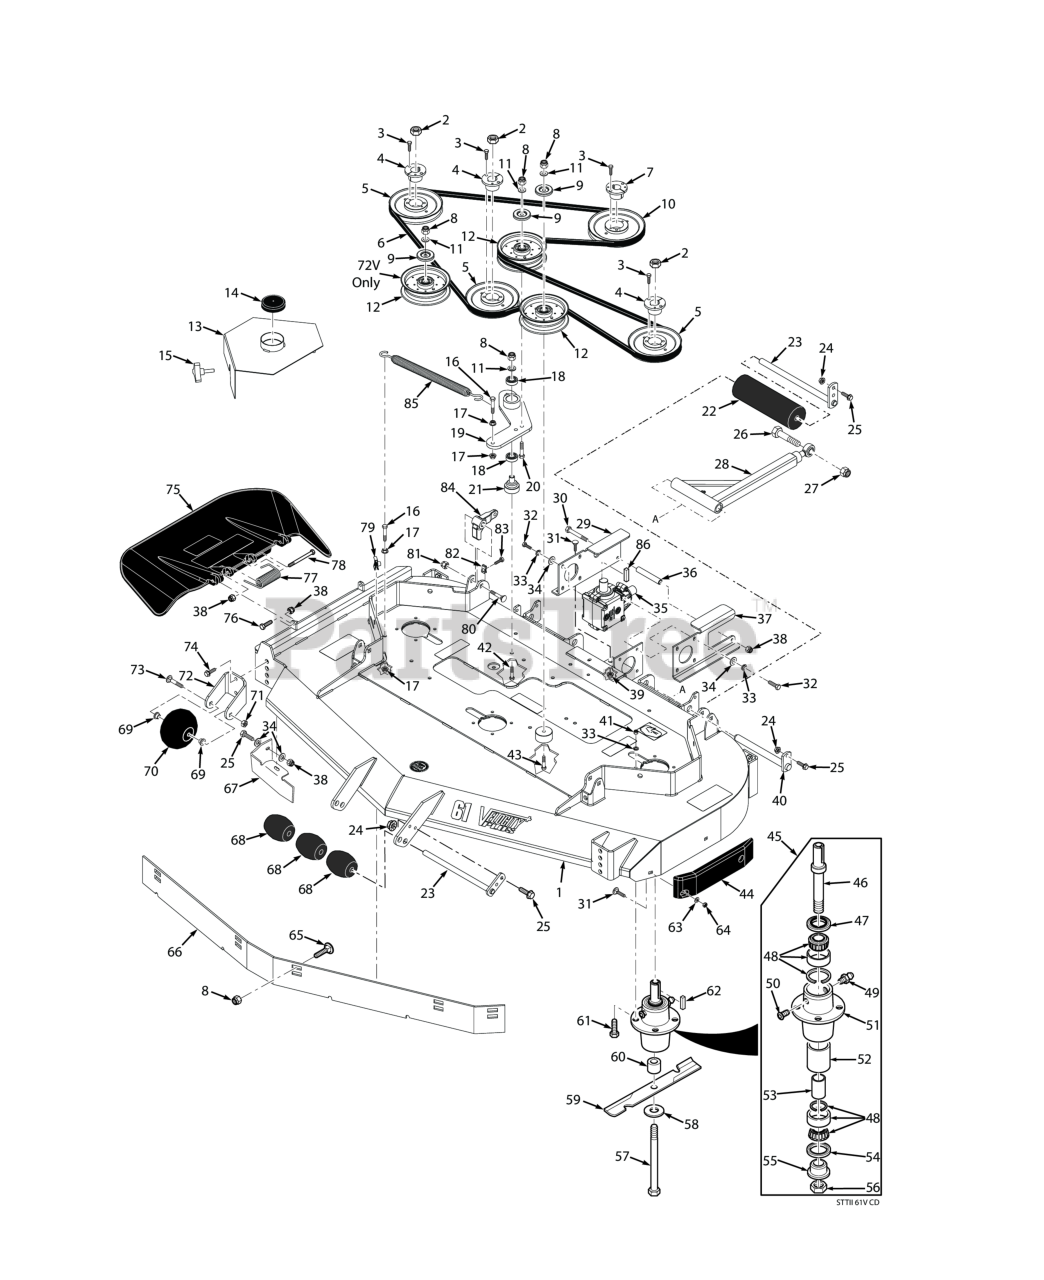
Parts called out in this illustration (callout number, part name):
1	Cutter Deck w/Decals - 72V
2	Hex Locknut, Elastic Stop, 3/8-16
3	Bolt, Hex Head 1/4-20 x 1" Grade 8 Black
4	Hub, Tapered 1-1/8" Bore
5	Pulley, 6.35 O.D. (Diesel Engine)
6	Belt, Cutter Deck Drive - Kubota
7	TAPERED HUB, 1.00" BORE
8	HEX NUT, ELASTIC STOP LOCK, 3/8-16
9	Quick Pin, 5/16" Dia.
10	Pulley, 6.75 O.D. - 61"
11	Flatwasher, 3/8 (.391 x .938 x .105 HD) Grade 8
12	Idler Pulley, Belt Clutch
13	Belt Cover, 61V (incl. #14)
15	Knob, w/stud 3/8-16 x 1-1/4"
16	Bolt, Hex Head 3/8-16 x 1-1/2" Grade 8 Black
17	NUT, 3/8-16 SERRATED FLANGE HEX HEAD
18	BEARINGS, BALL, NEUTRAL RETURN
19	Idler Arm, Cutter Deck
20	Capscrew, Hex Head 3/8-16 x 2.75"
21	Pivot, Idler - Short
22	Wheel, Anti-ScalpRelief Fitting, Tapered Spindle
23	Shaft Weldment, Guide Roller
24	Nut, Flange Head Elastic Stop 5/16-18
25	Bolt, Heax Head 5/16-18 x 1" (48V / 52V)
26	BOLT, HEX HEAD 5/8-11 X 4-1/2"
27	HEX LOCKNUT, ELASTIC STOP, 5/8-11
28	Push Arm (Includes 64,60,62)
29	Mounting Plate
30	Bolt, 5/16-18 x 4-3/4" Hex Head
31	Bolt, 5/16-18 x .75 RHSN Carriage
32	Bolt, Heax Head 5/16-18 x 1" (48V / 52V)
33	Lockwasher, 5/16 (.317 x .586 x .078) Helical Spring
34	Flatwasher, 5/16-.375 x .875 x .083 (35BV & 37BV-EFI)
35	Gearbox Assembly, Deck Drive
36	Spacer, Gearbox Mount
37	Mounting Plate
38	HEX NUT, ELASTIC STOP LOCK, 5/16-18
39	Nut, Serrated Flange 5/16-18 (Right Front Engine Mounting, Briggs and Kohler Only)
40	Shaft Weldment, Pusharm
41	Lock Nut, 5/16-18 Elastic Stop Grade 8
42	Bolt, Hex Head 3/8-16 x 3" - 52"
43	Capscrew, Hex Head 3/8-16 x 3-3/4"
44	Pad, Deck Wear
45	Cutter Spindle Assembly
46	Spindle Shaft, Tapered Brng
47	SEAL, 2.00 O.D. X 1.50 BORE
48	Tapered Bearing Set (Two Bearings W/Race)
49	GREASE FITTING, STR. 1/4-28 SELF TAP.
50	RELIEF FITTING, TAPERED BEARING SPINDLE
51	Housing, Spindle
52	Spacer, Outside, Cutter Spindle
53	SLEEVE, CUTTER SPINDLE
54	Seal, 2.00" O.D. x 1.625" Bore
55	SPINDLE BUSHING, BOTTOM
56	Nut , Spec ial 1 -1/ 1 6 - 1 8
57	BOLT, HEX HEAD, 5/8-11 X 9-1/2 GR.5
58	Flatwasher, 5/8-.688 x 1-3/4 x .134 HD
59	Cutter Blade, 21" Standard
60	Spacer, Spindle Bottom
61	Bolt, Hex Head 5/16-18 x 1-3/4" Grade 8
62	Key, 1/4 x 1/4 x 2.0"
63	Flatwasher, 5/16-.344 x .688 x .065 (48V / 52V)
64	Nut, Center Lock, 5/16-18(32)
65	Carriage Bolt, 3/8-16 x 1.0"
66	Baffle Custom-Cut, 61V (7-Position)
67	Turbo Baffle, Bolt On
68	Wheel, Anti-Scalp
69	Bushing, .376" I.D. Oilite
70	Bolt, Carriage 3/8-16 x 4"
71	Bolt, Hex Head 3/8-16 x 1" Ser. Flg.
72	Bracket, Anti-Scalp Wheel
73	Bolt, Hex Head 3/8-16 x 3-1/2"
74	Capscrew, 3/8-16 x 1.0" Serrated Flange Hex Hd
75	Discharge Chute Advantage - Large
76	Bolt, Hex Head 5/16-18 x 1-1/2" - Front
77	Spring, Discharge Chute
78	Bolt, 5/16-18 x 4-3/4" Hex Head
79	U-Nut, 3/8-16
80	Bolt, Carriage 7/16-14 x 2-1/4"
81	HEX LOCKNUT, ELASTIC STOP, 7/16-14
82	U-Nut, 3/8-16 (short)
83	Bolt, Hex Head 3/8-16 x 2" Special Lock
84	Lever, Deck Level
85	Spring, Cutter Deck
86	Key, 1/4 x 1/4 x 1.25" Pulley Mtg.
